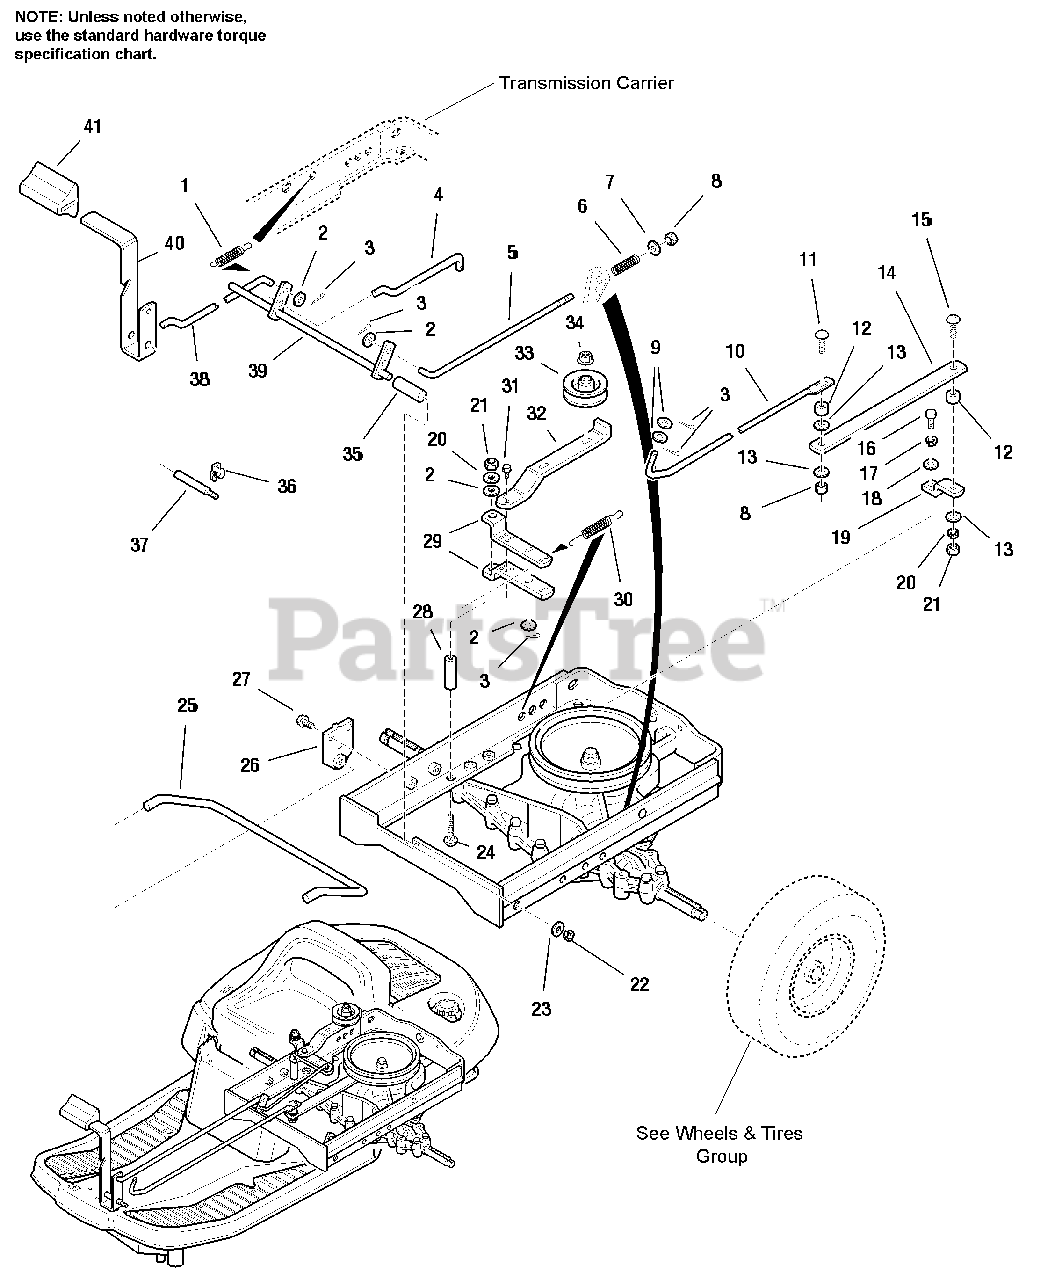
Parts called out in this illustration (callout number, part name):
1	SPRING, Return
2	WASHER, Plain
3	COTTER PIN, 3/32 x 3/4
4	ROD, Clutch, Rear
6	SPRING, Compression
7	WASHER, 5/16 x 1-1/4 x 1/16
8	NUT, Hex, Nylon Lock, 5/16-18
10	ROD, Shift, Front
11	CARRIAGE BOLT, 5/16-18 X 1-1/4
13	WASHER, Plain, 5/16
14	BAR, Shift, Rear
15	CARRIAGE BOLT, 5/16-18 x 1
16	SCREW, Hex Hd., 1/4-28 x 5/8
17	LOCKWASHER, 1/4
18	WASHER, Plain, 17/64 x 5/8 x 3/64
19	BRACKET, Shift
20	LOCKWASHER, 5/16
21	NUT, Hex, 5/16-18
22	KLIPRING, 1/2
23	WASHER, Plain, 1/2
24	CARRIAGE BOLT, 5/16-18 x 2-3/4
25	TORSION BAR
26	BRACKET, Torsion Bar
27	SCREW, Hex Hd., Flange, Taptite, 5/16-18 x 1/2
28	SPACER, Pivot
29	CLEVIS, Idler, Bracket
30	SPRING, Idler
31	SCREW, Hex Hd., Flange, Taptite, 1/4-20 x 5/8
32	LEVER, Idler, Pulley
33	PULLEY, Idler
34	NUT, Hex, Flange Lock, 3/8-16
35	TUBE, Plastic
36	KLIP RING, 3/8
37	PIVOT, Brake
38	ROD, Clutch, Front
39	PIVOT SHAFT ASSY.
40	LEVER, Clutch
41	PAD, Pedal
